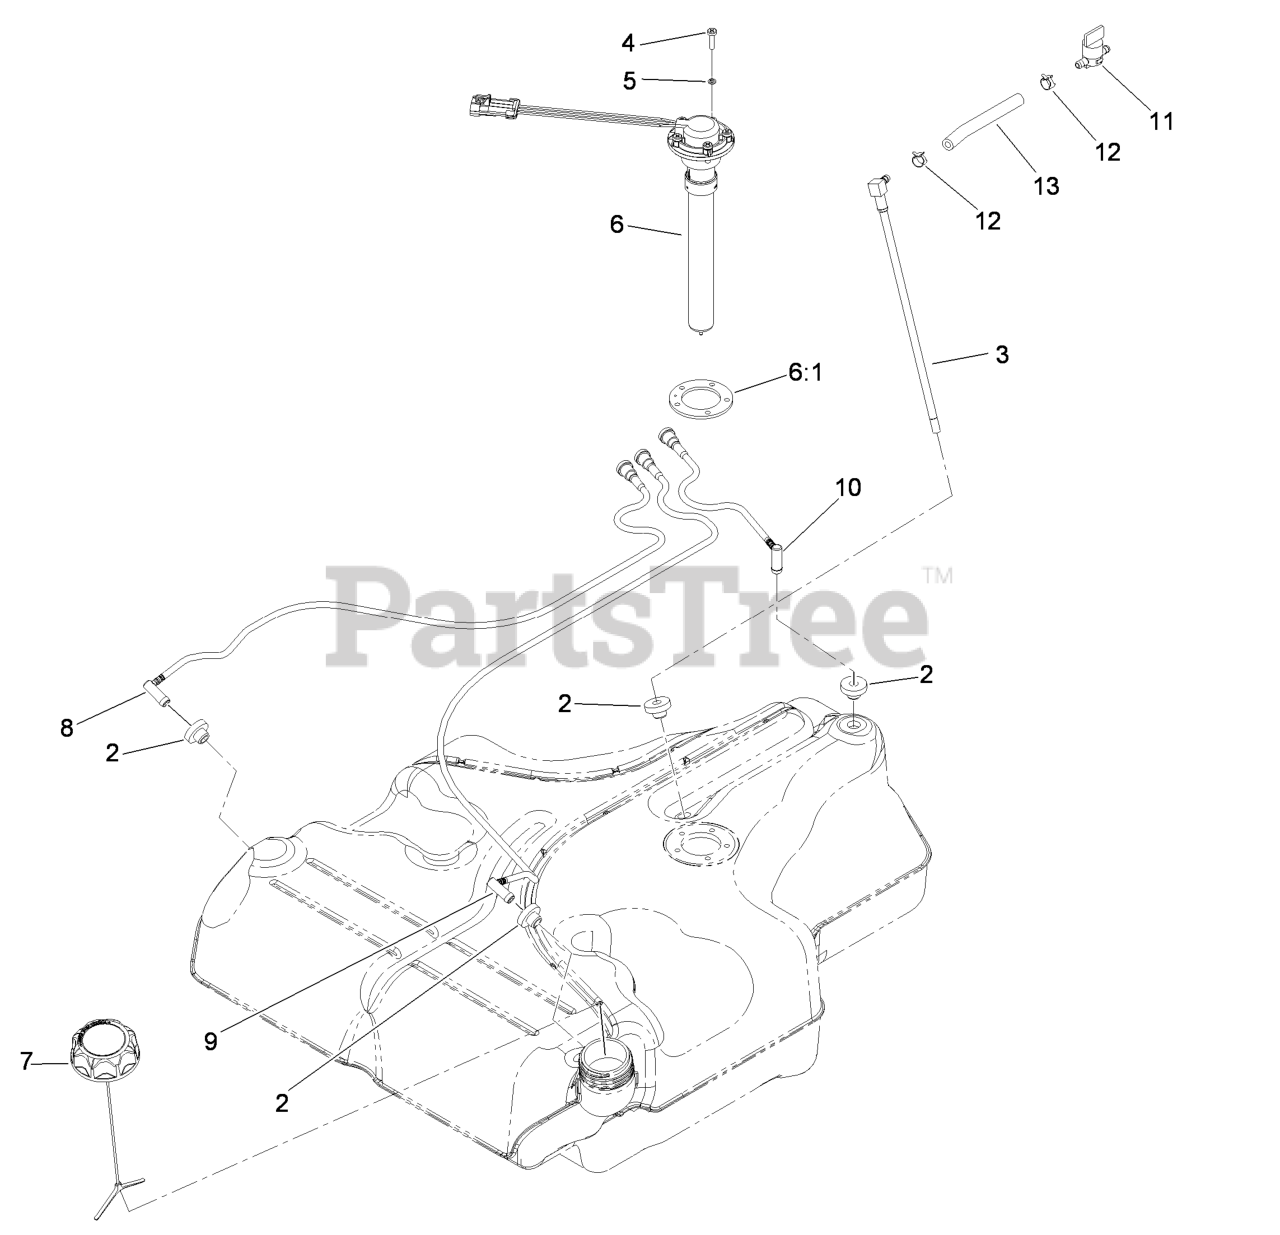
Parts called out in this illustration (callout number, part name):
2	BUSHING
3	FUEL LINE KIT (WITH GROMMET)
4	SCREW-PAN
5	WASHER-LOCK
6:1	GASKET-SENDER, FUEL
8	RH VENT LINE KIT (WITH GROMMET)
9	LH VENT LINE KIT (WITH GROMMET)
10	REAR VENT LINE KIT (WITH GROMMET)
11	VALVE-FUEL
12	CLAMP-HOSE
13	HOSE-FUEL
